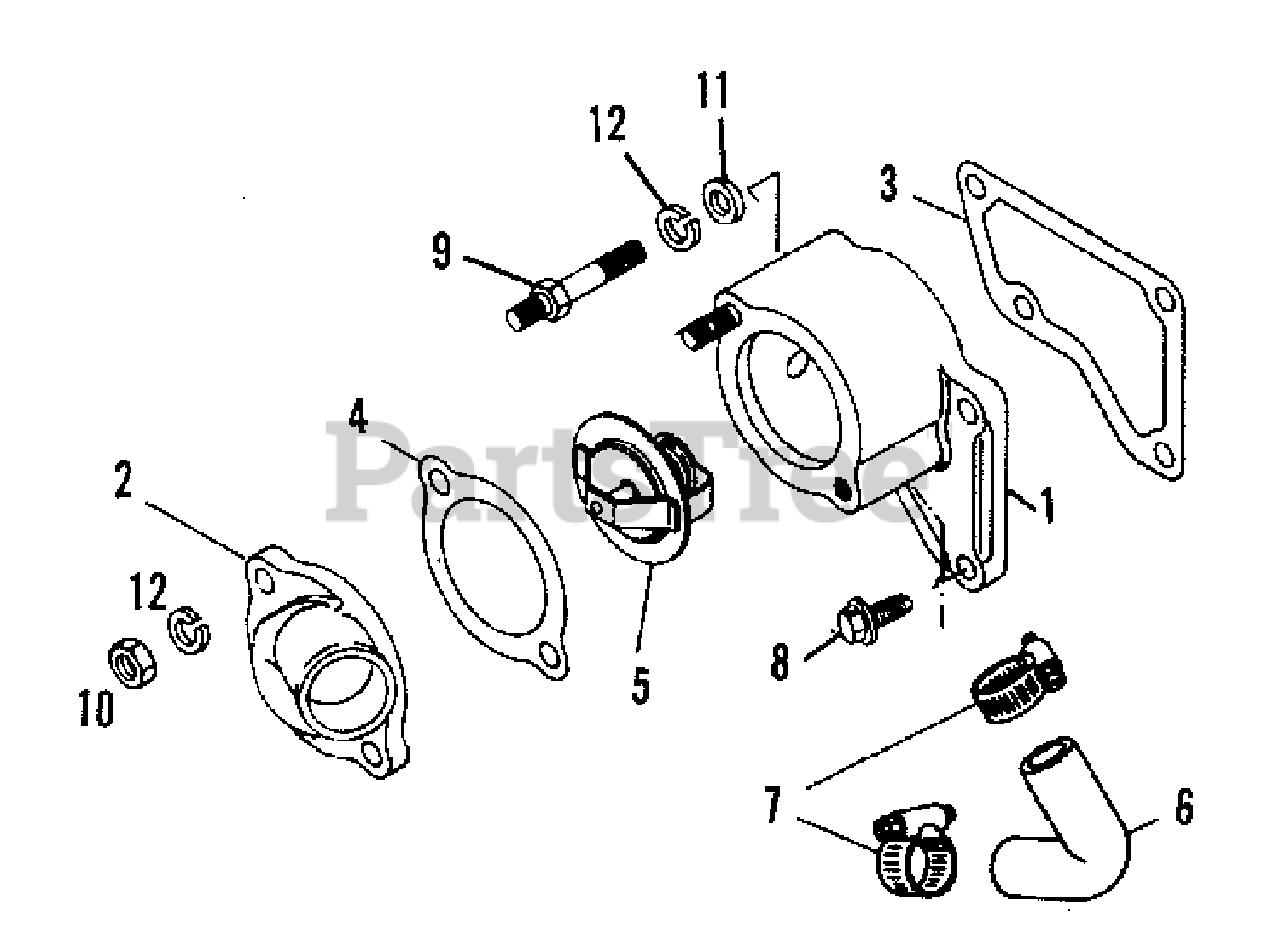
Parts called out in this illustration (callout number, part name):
1	HOUSING, thermostat (Incl. STUD)
1	STUD, M8 x 36
2	FLANGE, water outlet
5	THERMOSTAT KIT
6	HOSE, by-pass
7	CLAMP, by-pass hose
8	CAPSCREW, M8 x 22 w/washer, lockwasher
9	CAPSCREW, M8 x 58
11	WASHER, M8
12	LOCKWASHER, M8
